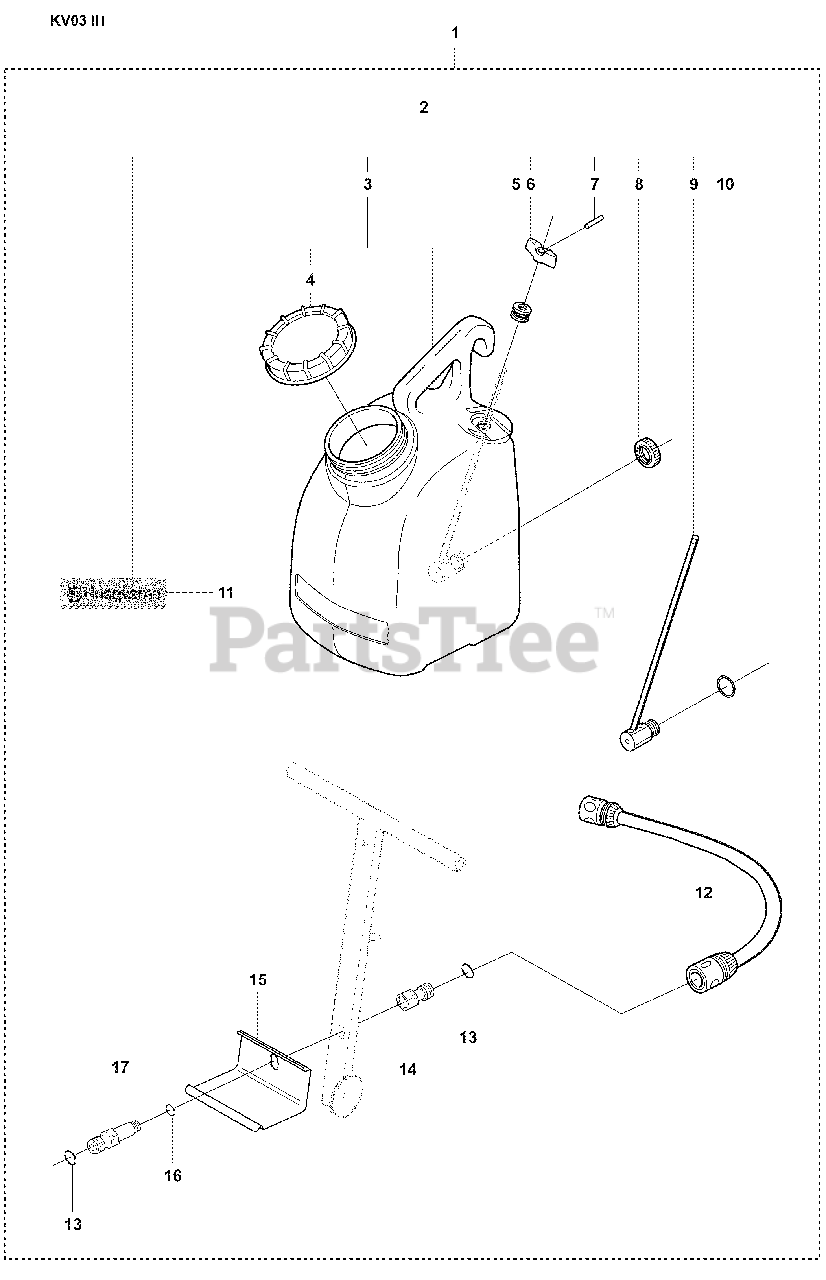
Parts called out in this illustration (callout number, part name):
1	WATER TANK CPL.
2	WATER TANK
3	WATER TANK
5	ANTIVIBE ELEMENT
12	HOSE
